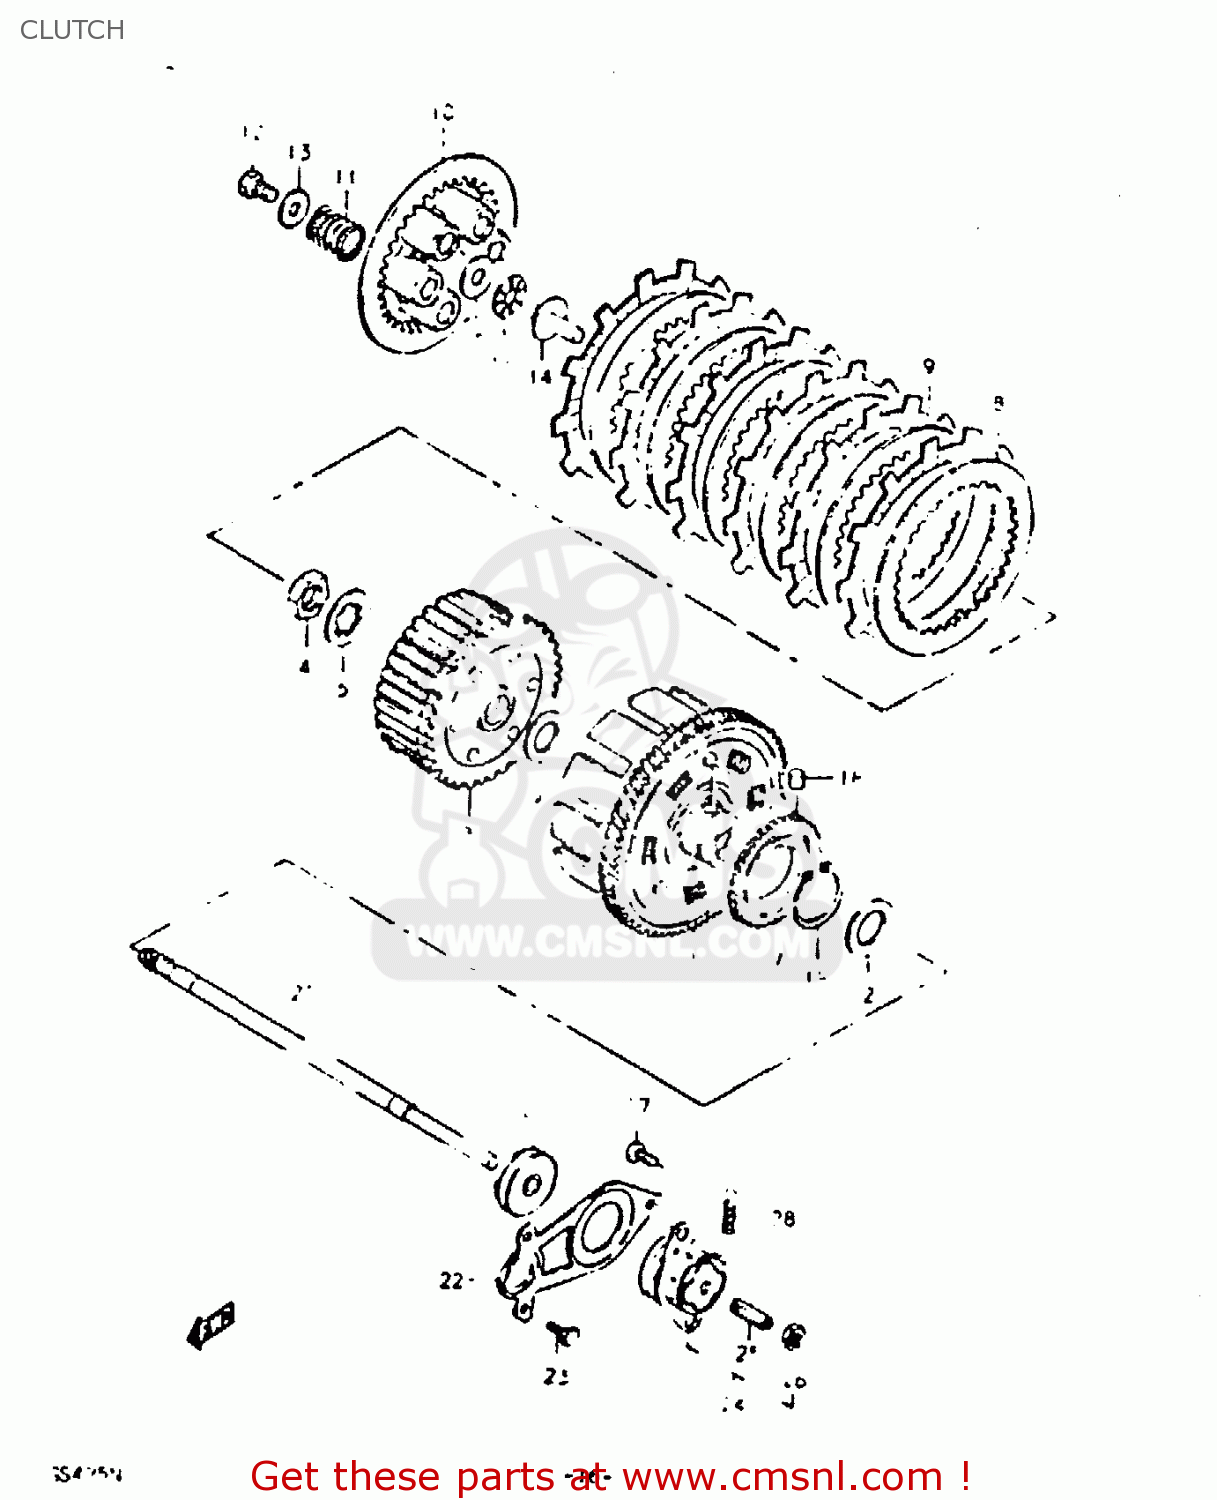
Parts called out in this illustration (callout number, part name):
1	GEAR ASSEMBLY,PRIMARY DRIVE
2	WASHER
3	HUB,CLUTCH SLEEVE
4	NUT (20MM)
5	WASHER,LOCK
6	WASHER(20X38X2)
7	PLATE,CLUTCH DRIVE (NAS)
8	PLATE,CLUTCH DRIVEN(T:2.0) (NAS)
9	PLATE,CLUTCH DRIVEN (NAS)
10	DISC,CLUTCH PRESSURE
11	SPRING
12	BOLT, UPPER
13	WASHER
14	PIECE,CLUTCH PUSH
15	BEARING(15X28X2)
16	WASHER
17	GEAR,OIL PUMP DRIVE
18	PIN(6X6)
19	CIRCLIP
20	ROD,CLUTCH PUSH
21	OIL SEAL
22	RETAINER,CL PUSH ROD OIL SEAL
23	BOLT
24	SCREW ASSEMBLY,CLUTCH RELEASE
25	SCREW
26	NUT 6MM
27	SCREW 6X12
28	SPRING
